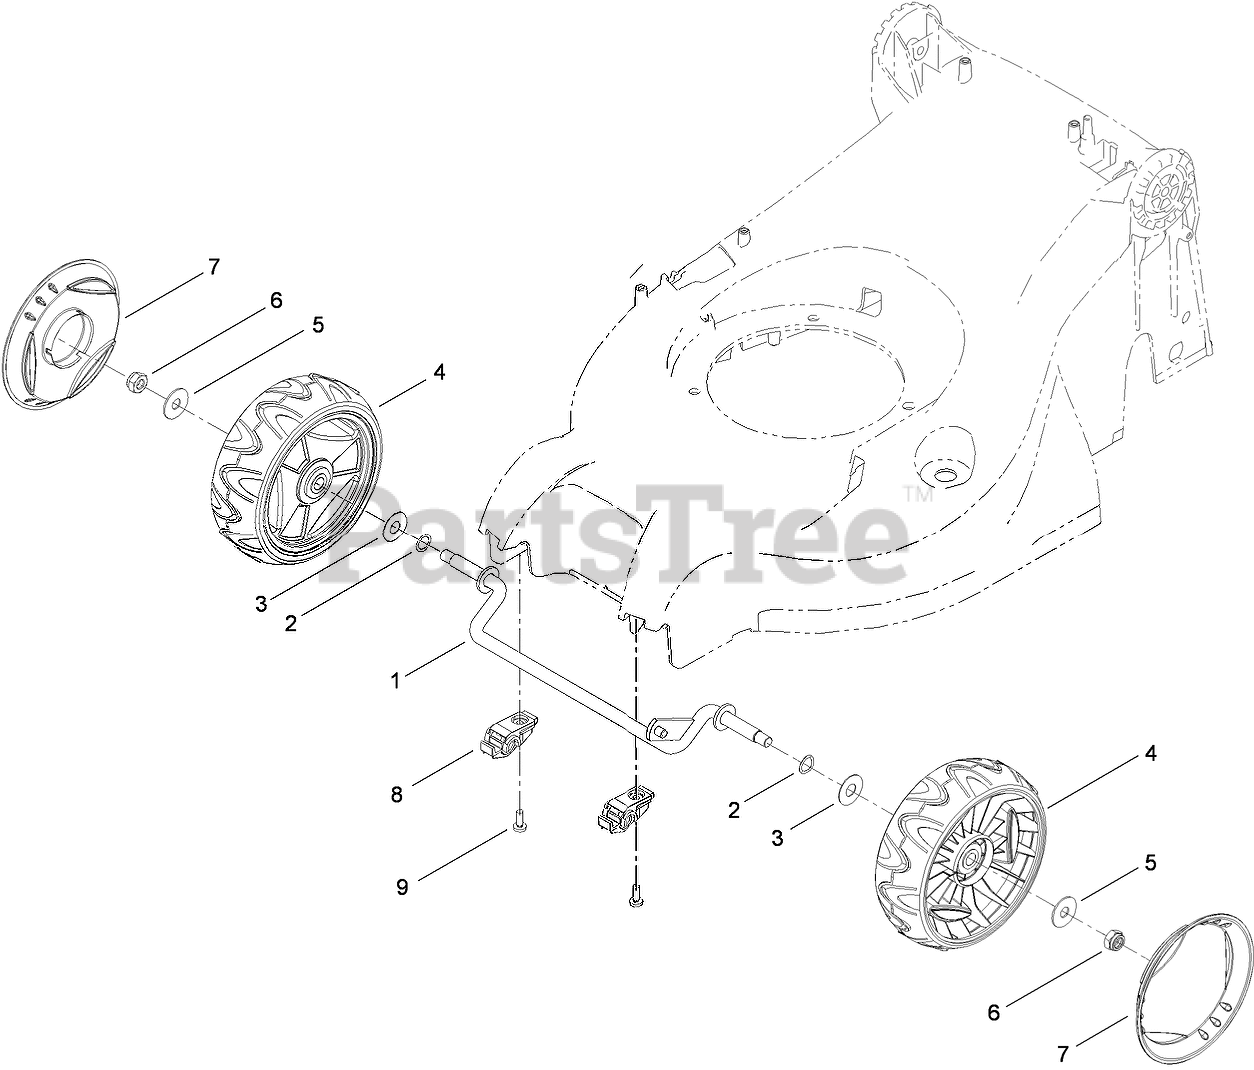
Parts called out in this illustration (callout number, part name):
1	FRONT AXLE ASM
2	WASHER-SPRING
3	WASHER-PLAIN
4	FRONT WHEEL ASM
5	WASHER-PLAIN
6	NUT-HH
7	COVER-WHEEL, FRONT
8	CLAMP-AXLE, FRONT
9	SCREW-SPH, THREAD ROLLING
